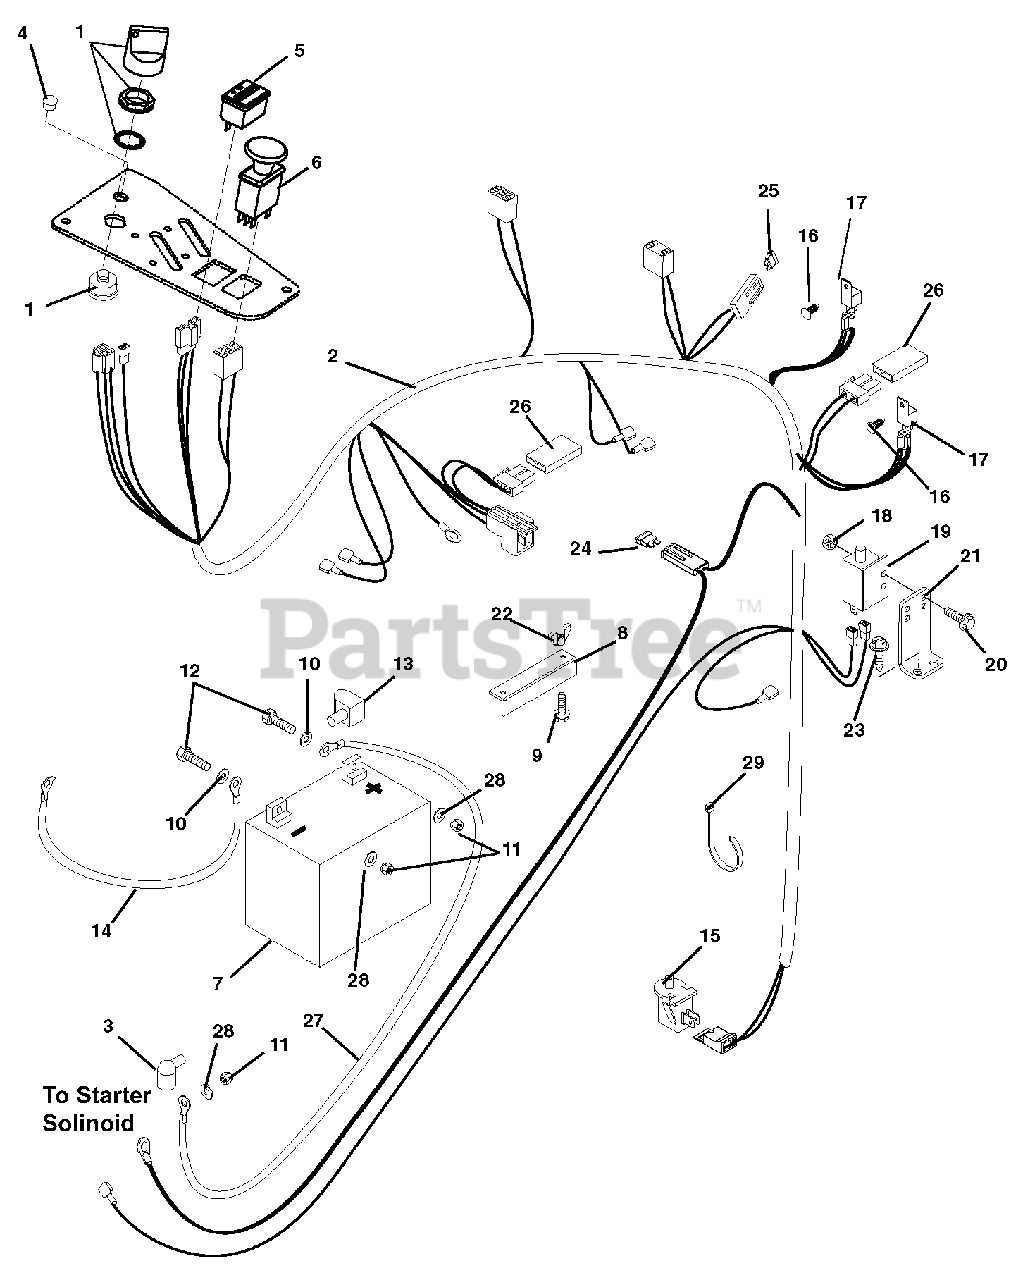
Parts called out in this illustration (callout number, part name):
1	Key Switch
2	Harness, CZ Remote Solenoid
3	Boot, Eyelet Terminal
4	Plug, Hole .50 Diameter
5	Hour Meter – w/Maintenance
6	Switch, Clutch With Retainer Ring
8	Hold Down
9	Bolt, Round Head Square Neck .25-20 x 7.50
10	Washer, Flat Steel .281 x .620 x .065
11	Nut, Hex .25-20
12	Bolt, Hex .25-20 x .75 Grade 5
13	Insulator
14	Cable, Negative Battery
15	Switch, Snap Mounting (N.O.)
16	Rivet, .25 Nylon Panel
17	Relay (Included with Harness)
18	Nut, Locking-Nylon 10-24 with Insert
19	Switch, Single Pole
20	Screw, Machine 10-24 x .75 Hex Washer Head
21	Mount, Brake Switch
22	Nut, Locking Wing .25-20
23	Screw, Tapping .25-20 x .50 Hex Washer Head
24	Fuse, 25 Amp (Included with Harness)
25	Fuse, 20 Amp
26	Diode, Connector Shell
27	Cable, Starter
28	Washer, Lock .25 x .062
29	Tie, Cable LG 5.50
